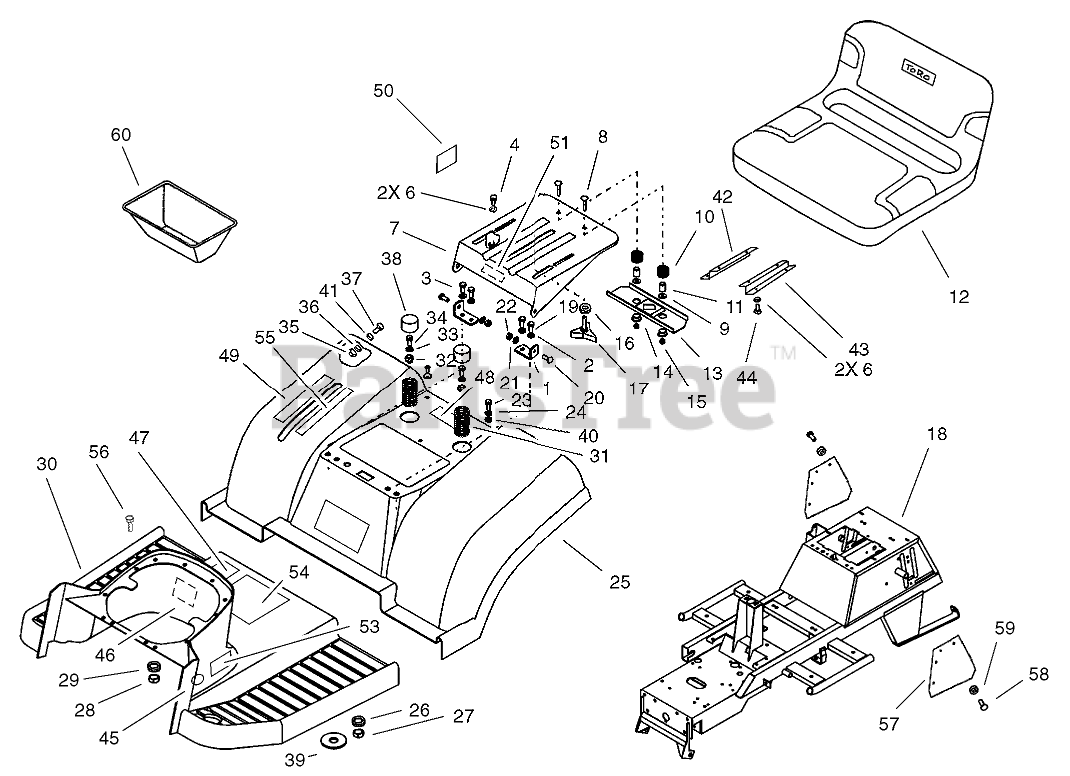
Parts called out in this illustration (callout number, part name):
1	BRACKET-SUPPORT, SEAT
2	WASHER-SPRING
3	SCREW-HH
4	BOLT-HEX
6	WASHER-SPRING
7	SUPPORT-SEAT
8	BOLT-CARRIAGE
9	WASHER-FLAT
10	SPRING-SEAT
11	SPACER-SPLIT
12	SEAT-V-511
13	BRACKET
14	BUSHING
15	NUT-LOCK
16	WASHER-SPRING
17	KNOB-ADJUSTMENT
18	FRAME-CHASSIS
19	SCREW-HH
20	SCREW-SUPPORT, SEAT
21	WASHER-PLAIN
22	NUT-LOCK, NI
23	SCREW-HSFH
24	WASHER-FINISH
25	Fender
26	WASHER-FLAT
27	NUT-LOCK, NI
28	NUT-LOCK
29	WASHER-FLAT
30	FOOTREST ASM
31	SPRING-SEAT
32	NUT-LOCK, NI
33	WASHER-PLAIN
34	SCREW-HH
35	NUT-LOCK
36	WASHER-FLAT
37	BOLT-CARRIAGE
38	CAP-HUB
39	WASHER-RUBBER
40	WASHER-RUBBER
41	WASHER-RUBBER
42	BRACKET-RIGHT SEAT
43	BRACKET-LEFT SEAT
44	Screw
45	DECAL-BRAKE, PARKING
46	DECAL-STARTING
47	DECAL-OPERATION, HYDRO
48	DECAL-BAG TO FRAME
49	DECAL-HOC, RH
50	DECAL-SWITCH
51	DECAL-DANGER
53	DECAL - TOWER 190DH
54	DECAL-INSTRUCTION
55	DECAL-HOC, LH
56	SCREW-HH
57	Cover-Rear
59	Washer-Flat
60	Box-Battery
